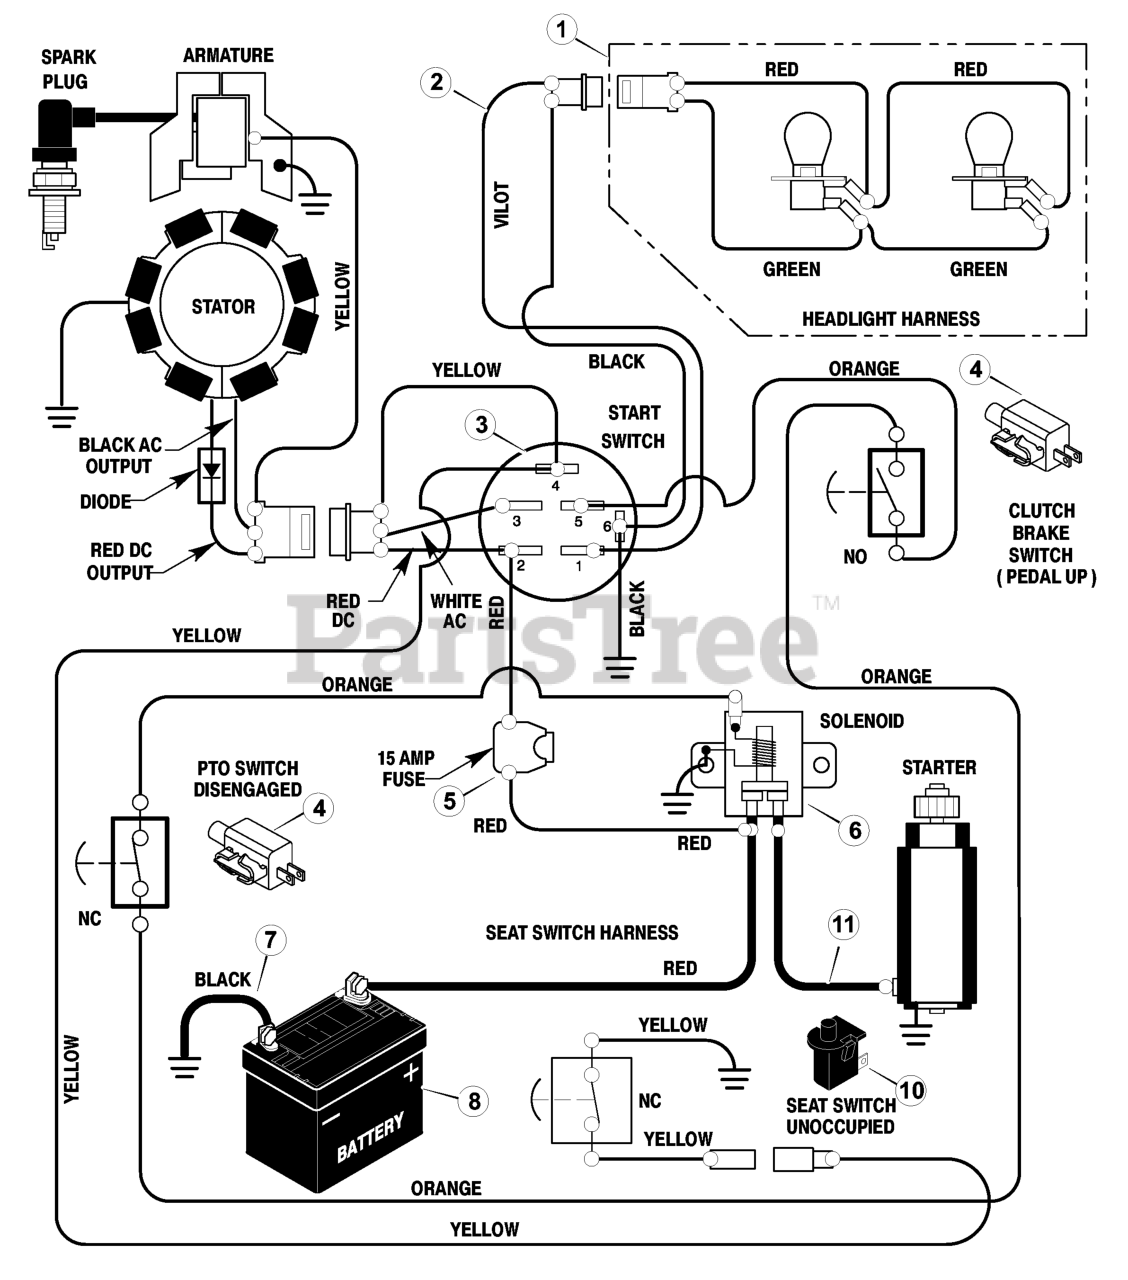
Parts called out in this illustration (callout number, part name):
1	Harness, Light Wire
2	Harness, Chassis Wire
3	Switch, Ignition
4	Switch, Limit
6	Solenoid
7	Cable, Battery Ground
8	Battery
10	Switch, Seat Sensor
